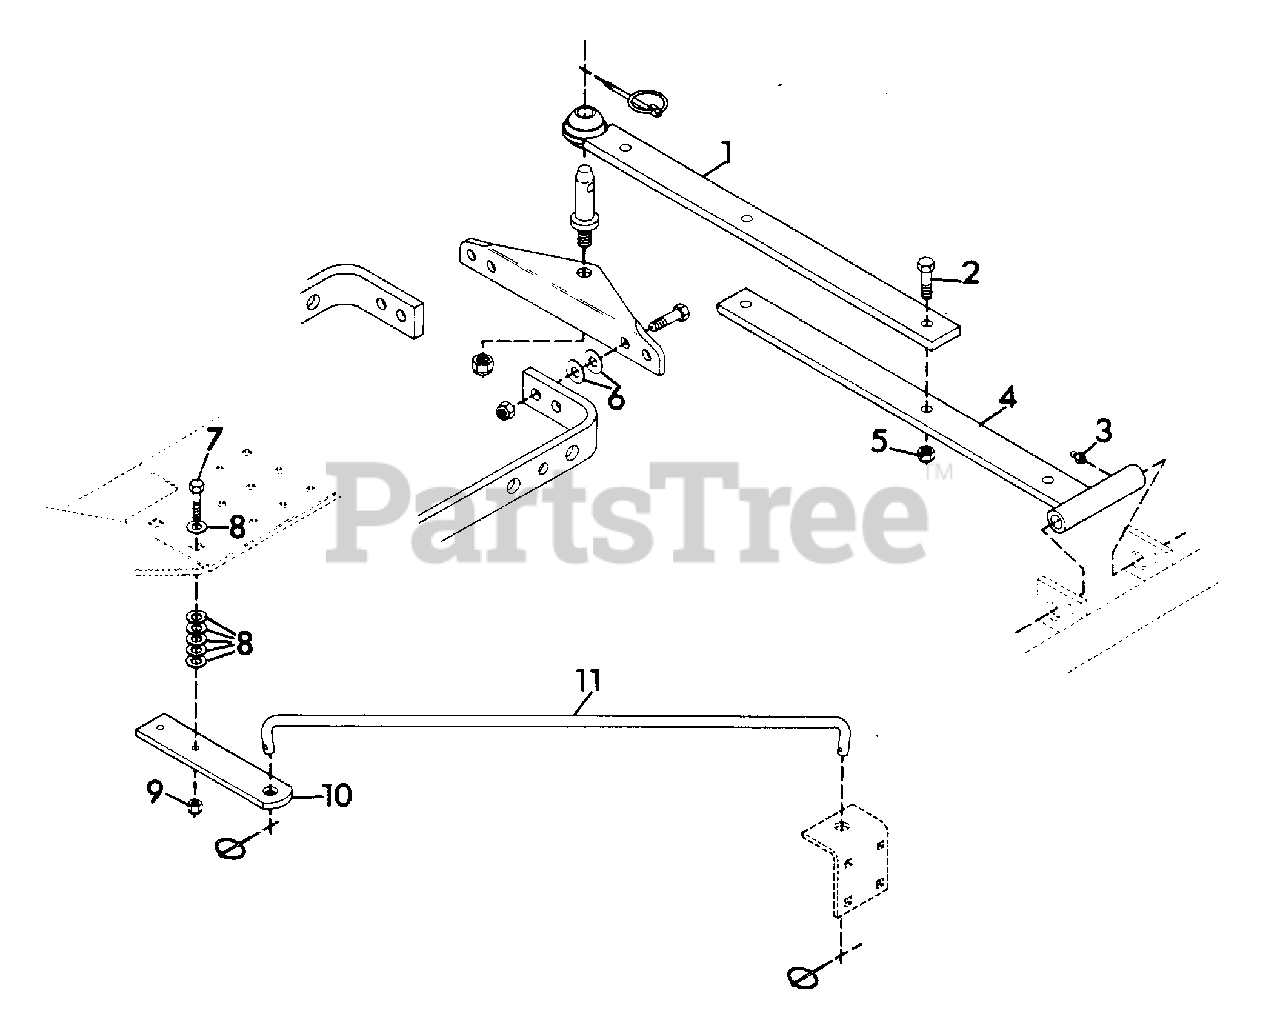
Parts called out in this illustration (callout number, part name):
1	WELDMENT, REAR BALL JOINT
2	BOLT, HEX 1/2-13X1.75
3	FITTING, LUBE 1/4-28
4	WELDMENT, REAR JOINT
5	NUT, LOCK 1/2-13
6	WASHER, FLAT .563X1.375X.109
7	BOLT, HEX 3/8-16X1.75
8	WASHER, FLAT .438X1.000X.083
9	NUT, LOCK 3/8-16
10	PLATE, SUPPORT
11	ROD, STABILIZER
11	ROD, STABILIZER 60"
